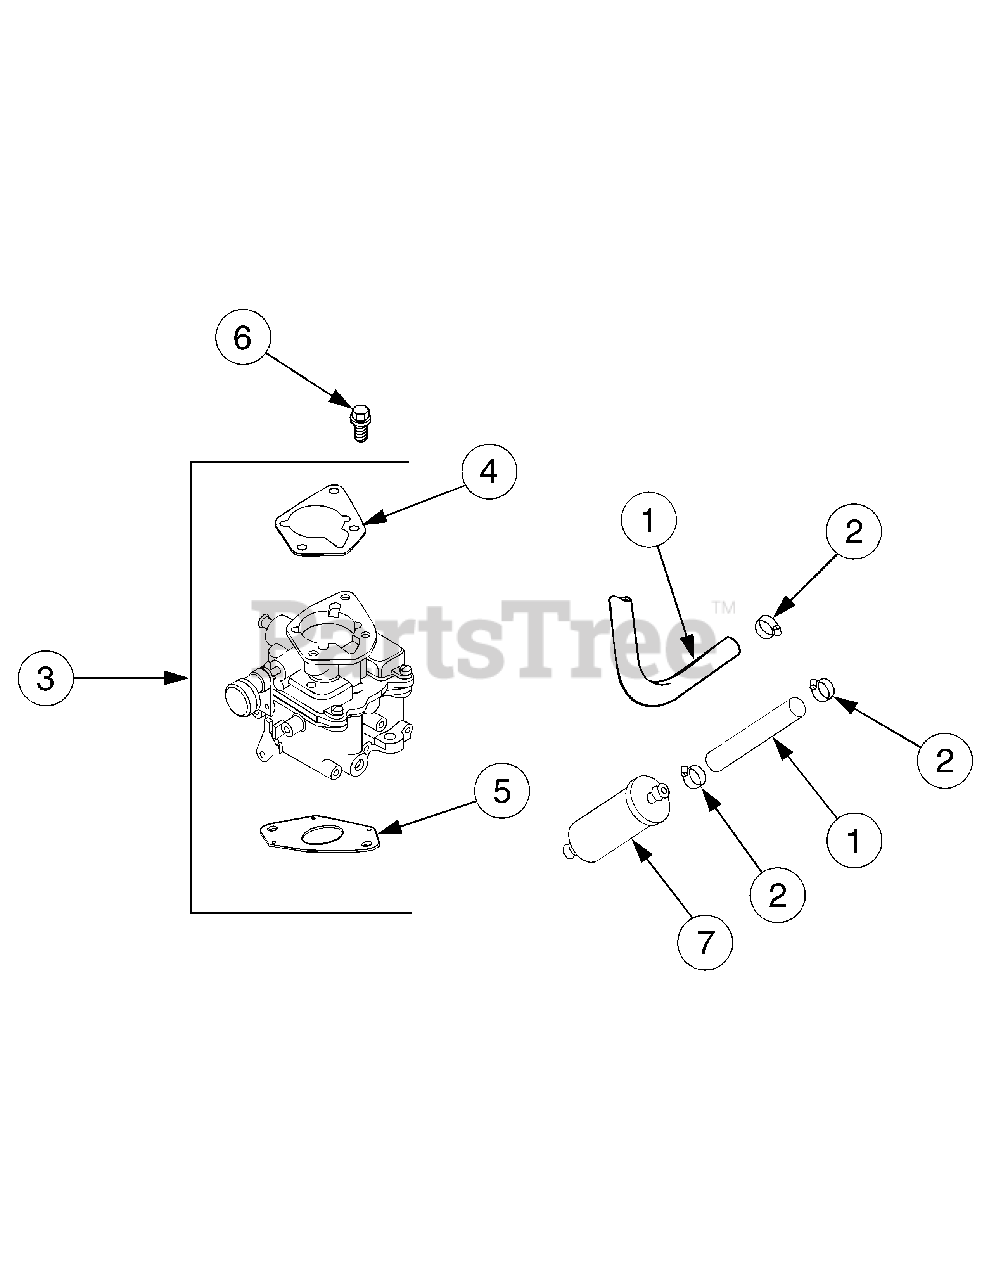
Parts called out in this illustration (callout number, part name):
1	Line, Fuel (24" - Cut to Length)
2	Clamp, Hose
3	Kit, Carburetor w/Gasket (Includes 2,3)
4	Gasket, Air Cleaner Base
5	Gasket, Carburetor
6	Screw, Hex Flange, M6 x 1.0 x 25
7	Filter, Fuel
